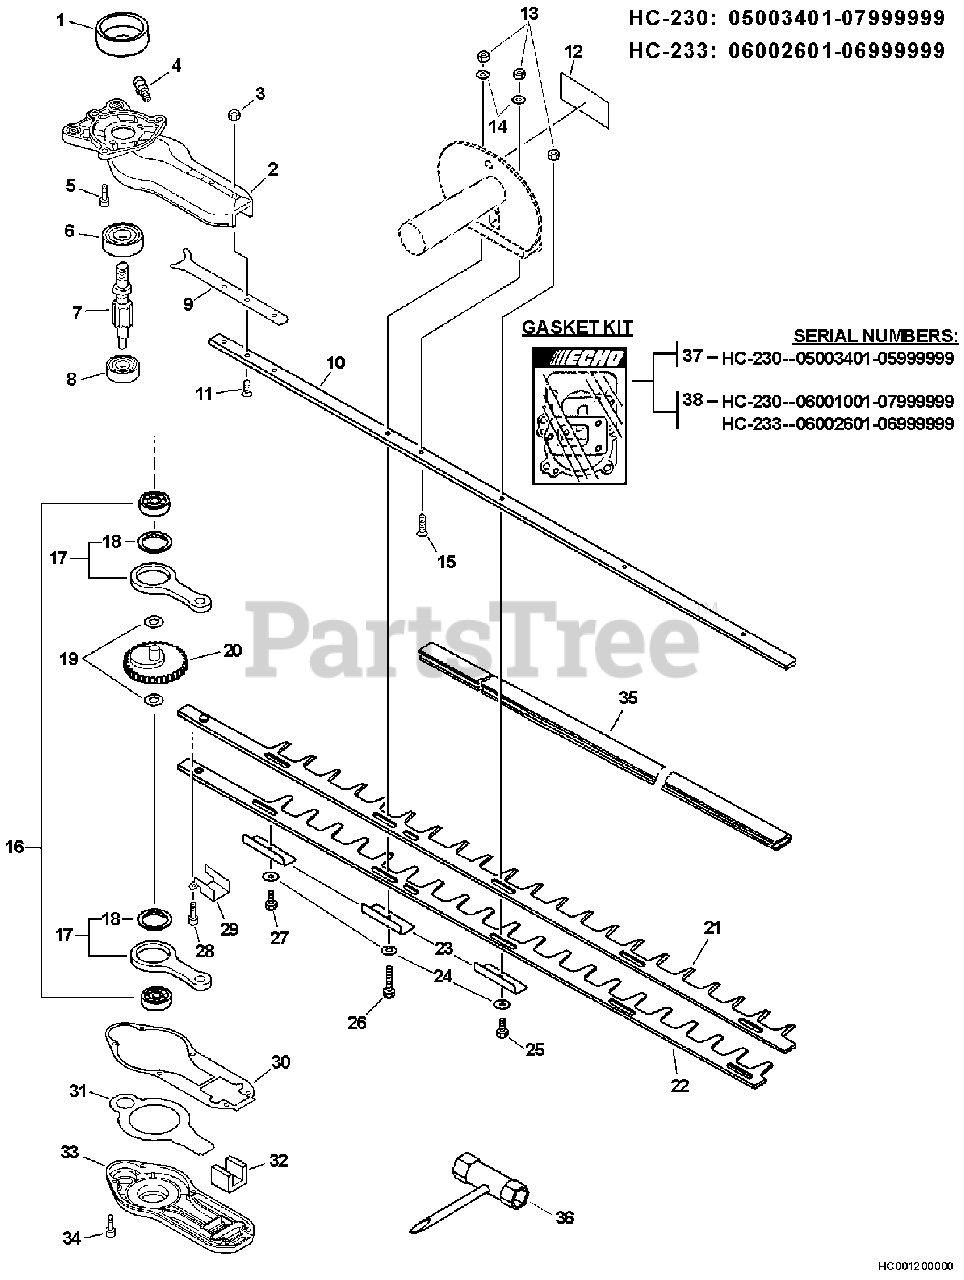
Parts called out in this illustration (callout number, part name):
1	DRUM, CLUTCH
2	CASE, GEAR - UPPER
3	NUT - 6 -- FLANGE
4	FITTING, GREASE
5	SCREW - 6X18
6	BEARING, BALL - 6200
7	GEAR - SPUR
8	BEARING, BALL - 608ZZ
10	SUPPORT, BLADE - 30" (76cm)
11	SCREW - 6X30
12	LABEL - CAUTION
13	LOCKNUT - 6
14	WASHER - 6
15	SCREW - 6X30
16	BEARING, BALL - 6200
17	ROD, CONNECTING
18	BEARING, NEEDLE
19	WASHER - 10
20	GEAR - SPUR
21	BLADE - 30" (76mm) -- UPPER
22	BLADE - 30" (76mm) -- LOWER
23	INSULATOR
27	BOLT - 6
28	SCREW - 4X16
29	GUIDE, BLADE
30	GASKET, GEAR CASE
31	PLATE, GEAR CASE
33	CASE, GEAR - LOWER
34	SCREW - 4X16
35	COVER, BLADE
36	T-WRENCH - 13X19mm
37	GASKET KIT
38	GASKET KIT
